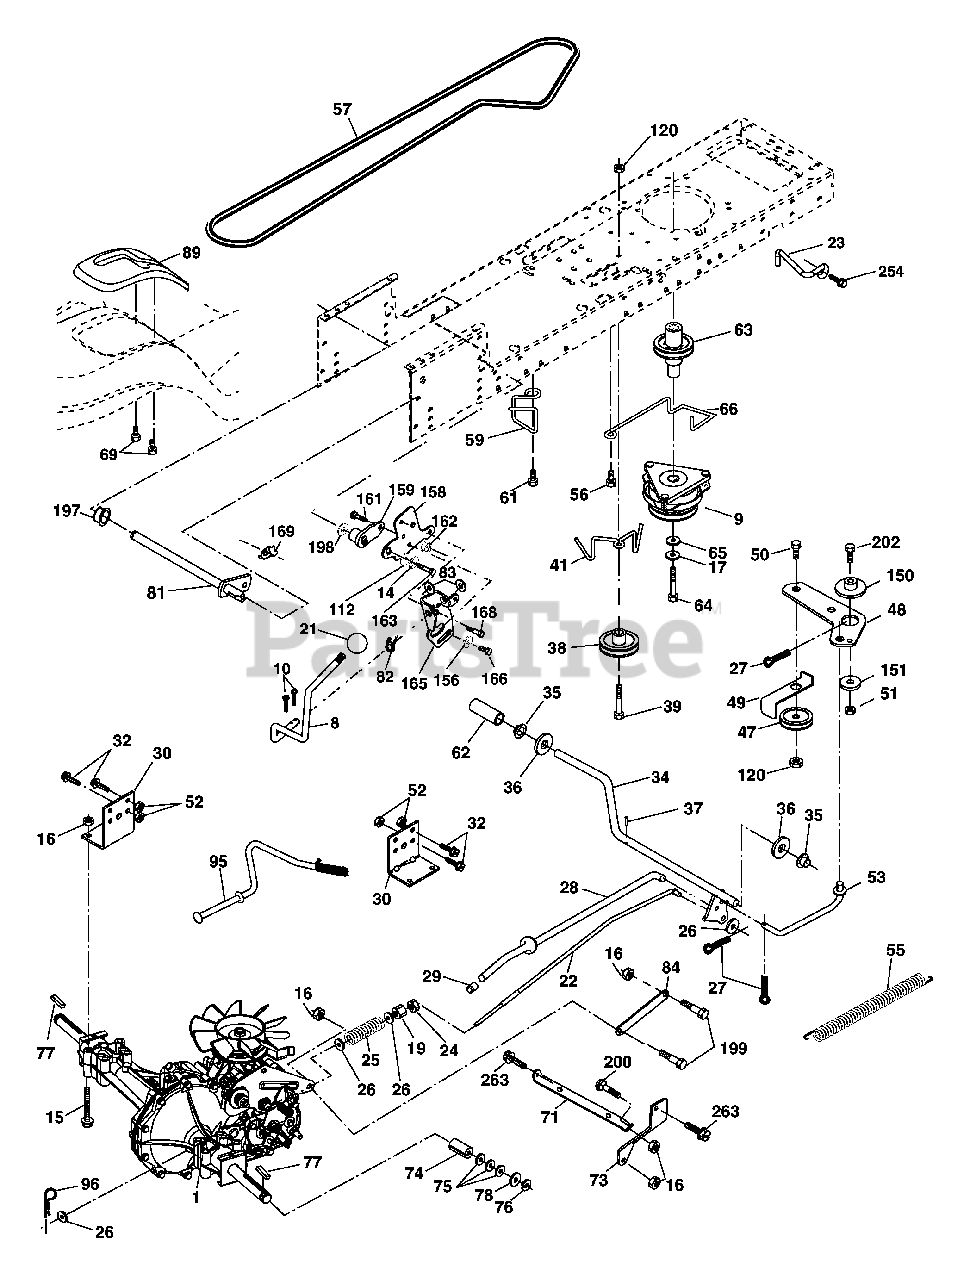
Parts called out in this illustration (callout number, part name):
8	Rod Shift
9	Clutch Electric
10	Pin Cotter 1/8 x 1 CAD
14	Washer Lock Hvy. Helical
15	Bolt, Hex FLGHD 5/16-18 Gr. 5
16	Nut Lock Hex W/Ins 5/16-18 unc P
17	Washer 1-1/2 OD x 15/32 ID x 2.50
19	Nut Lock Hex W/Wsh 3/8-16 unc
21	knob 1/2-13
22	Rod, Brake Hydro
23	Bracket Anti-Rotation
24	Nut Hex Jam 3/8-16
25	Spring, Brake Rod
26	Washer
27	Pin Cotter 1/8 x 3/4 CAD.
28	Rod, Parking Brake
29	Cap, Parking Brake
30	Bracket, Transaxle
32	Bolt Hex Hd 5/16-18 unc x 3/4
34	Shaft, Foot Pedal Nibbed
35	Bearing, Nylon
36	Washer 21/32 x 1 x 16 Ga.
37	Pin, Roll 3/16 x 1
38	Pulley, Idler, Composite
39	Bolt 3/8-16unc x 2-3/4
41	Keeper, Belt Retainer
47	Pulley, Idler, V-Groove
48	Bellcrank Clutch Grnd Drv STL
49	Retainer, Belt
50	Bolt Carr Sh 3/8-16 x 1-1/2 Gr.5
51	Nut Crownlock 3/8-16 unc
52	Nut Crownlock 5/16-18 unc
53	Link, Clutch
55	Spring, Return, Clutch
56	Screw 3/8-16 x 1.0
57	V-Belt, Ground Drive
59	Keeper, Center Span
61	Screw 3/8-16 x 3/4
62	Cover, Pedal
63	Pulley, Engine
64	Bolt, Hex
65	Washer Lock Hvy Hlcl Spr. 7/16
66	Keeper Belt Engine
69	Screw
71	Strap Torque Lh Hydro
73	Strap Torque Rh Hydro
74	Spacer, Split
75	Washer 25/32 x 1-1/4 x 16 Ga.
76	E-Ring
77	Key, Square
78	Washer 25/32 x 1-5/8 x 16 Ga.
81	Shaft Asm. Cross
82	Spring Torsion
83	Washer 17/32 x 3/4 x 16 Ga.
84	Link, Transaxle
89	Console, Shift
95	Control Asm Bypass Hydro
96	Retainer Spring 1" Zinc/Cad
112	Washer 9/32 x 3/4 x 10 Ga.
120	Nut Lock Flg 3/8-16 unc
150	Spacer Retainer
151	Washer 13/32 x 2 x 10 Ga.
156	Washer Srrted 5/16 ID x 1 x .125
158	Bracket Shift Mount
159	Hub Shift
161	Bolt Rdhd Sqnk 1/4-20 x 3/4 Gr. 5
162	Nut Crownlock 1/4-20 unc
163	Bolt Hex Fin 1/4-20 unc x 1 Gr. 5
165	Bracket Pivot Lever
166	Screw 5/16-18 x 5/8
168	Bolt Shoulder 5/16-18 x .561
169	Plate Fastening LT
197	Nyliner Snap-In 5/8" ID
198	Washer Nyl 7/8" ID x .105"
199	Bolt Shoulder 5/16-18 unc
200	Bolt Rdhd Sqnk 5/16-18 unc x 1
202	Bolt 3/8-16 x 1-3/4 Gr. 5
254	Screw 3/8-16 x 1
263	Screw 3/8-16 x .75
